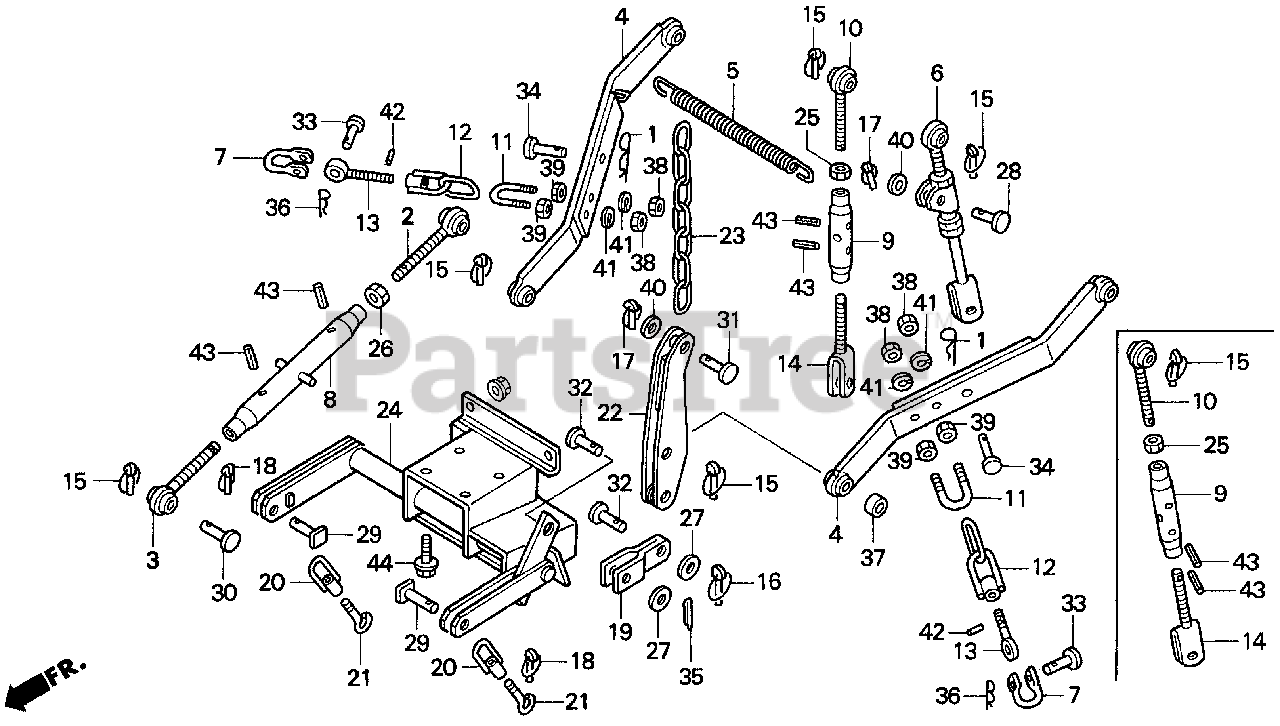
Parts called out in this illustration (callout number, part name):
2	HOLDER, R. LINK (UPPER)
3	HOLDER, L. LINK (UPPER)
4	LINK (LOWER)
5	SPRING, STOPPER
6	ROD, L. LIFT
7	JOINT, STABILIZER
8	BUCKLE, LINK TURN (UPPER)
9	BUCKLE, LIFT ROD TURN
10	ROD, R. LIFT (UPPER)
11	BOLT, STABILIZER (12MM)
12	NUT, STABILIZER JOINT (16MM)
13	BOLT, STABILIZER JOINT (16MM)
14	ROD, R. LIFT (LOWER)
15	LINCHPIN ASSY.
17	LINCHPIN ASSY.
23	CHAIN, LIFT LINK
25	NUT, HEX. (20MM)
26	NUT, HEX. (22MM)
28	PIN, RR. LINK
30	PIN (19X76)
31	PIN, RR. LINK
33	PIN, LIFT ARM (10X51.5)
34	PIN, LINK (LOWER)
37	COLLAR, ADJUSTING (1/2")
38	NUT, HEX. (12MM)
39	NUT, HEX. (12MM)
40	WASHER, PLAIN (16MM)
41	WASHER, SPRING (12MM)
42	PIN, SPRING (3X18)
43	PIN, SPRING (4X22)
